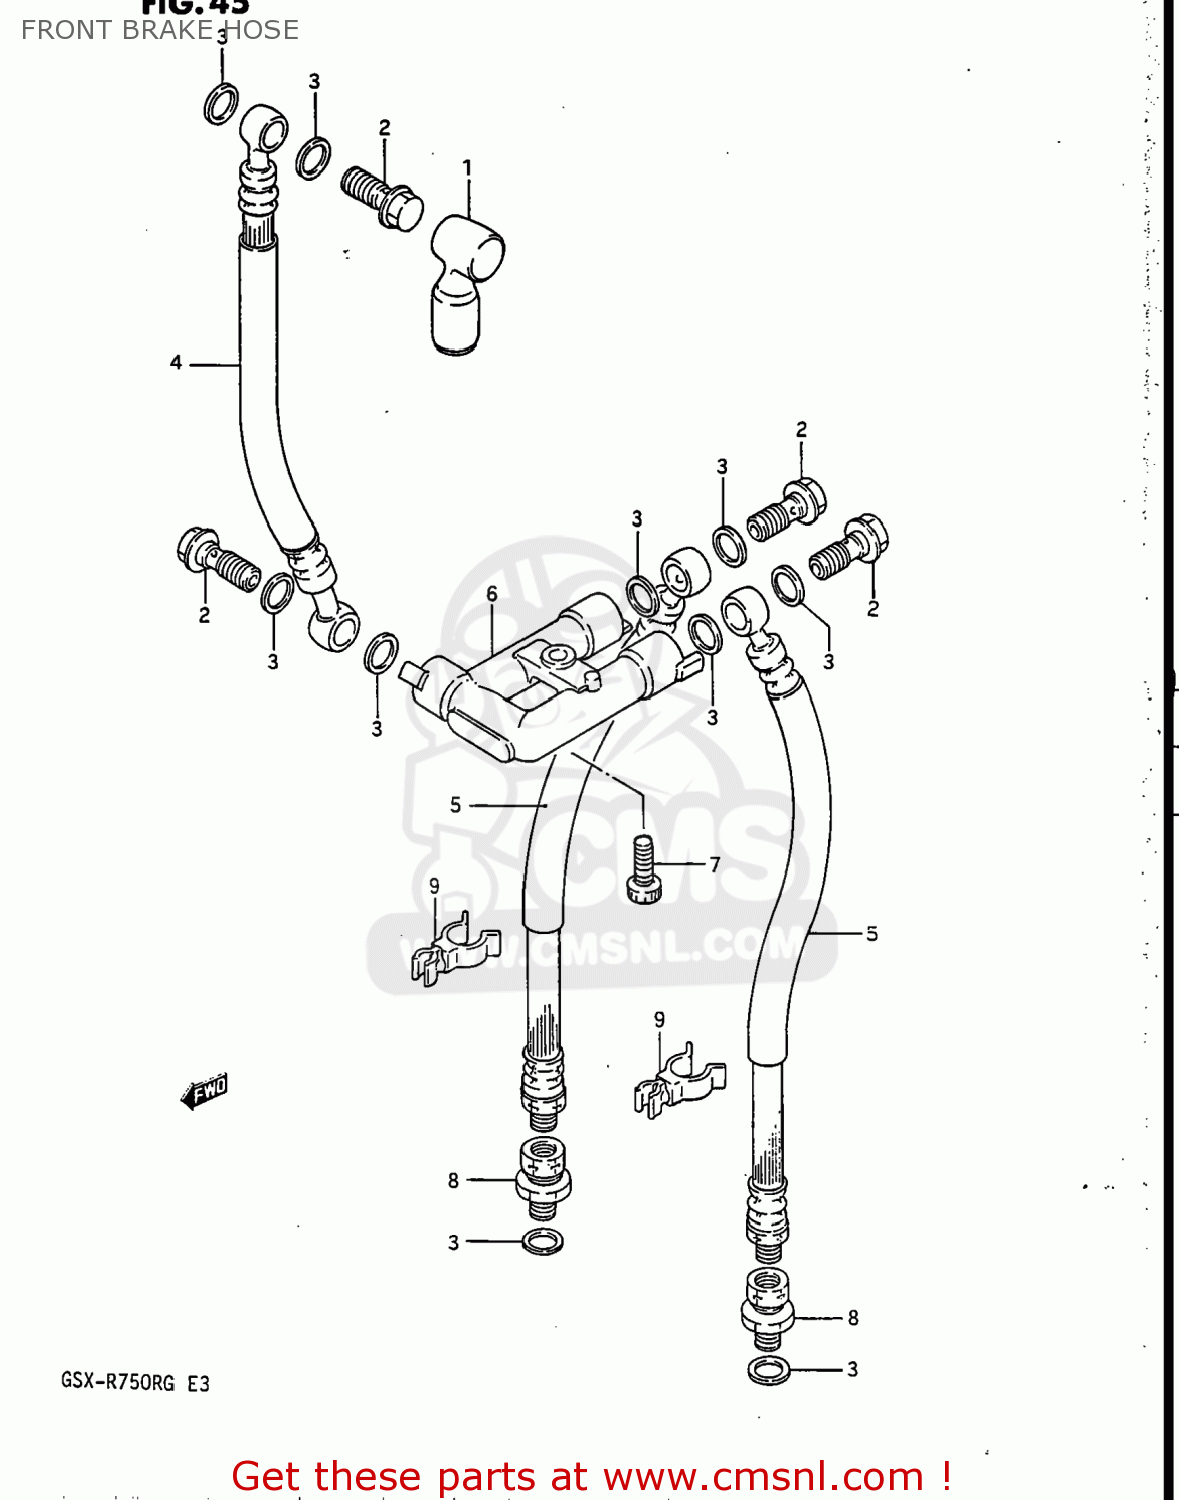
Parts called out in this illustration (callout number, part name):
1	BOOT,MASTER CYLINDER
2	BOLT UNION
3	WASHER(10X15X1.5)
4	HOSE,FRONT BRAKE NO.1
5	HOSE,FR BRAKE NO.2
6	JOINT,BRAKE HOSE
7	BOLT
8	ADAPTER,BRAKE HOSE
9	CLAMP
